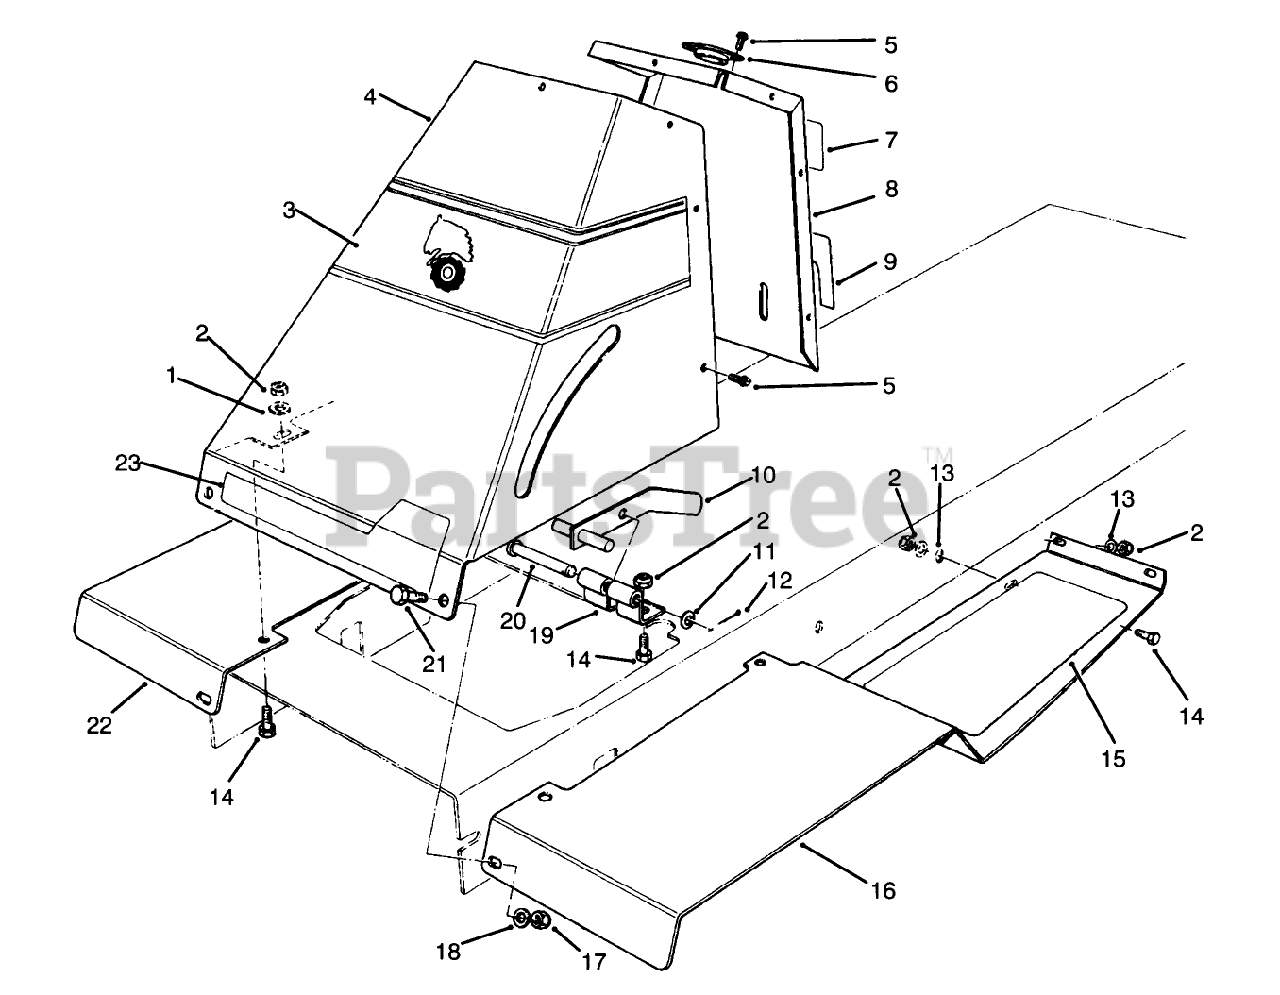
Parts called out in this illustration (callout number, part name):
1	WASHER-FLAT
2	NUT-LOCK, NI
3	DECAL - STEERING SUPT
5	SCREW-HWHTF
6	GUIDE-STRG SHAFT
7	DECAL-DANGER
9	PARK BRAKE DECAL
10	PARKING BRAKE WA *B
11	WASHER-FLAT
12	PIN-COTTER
13	WASHER-PLAIN
14	SCREW-HH
15	FOOT TREAD L.H.
17	NUT-LOCK, NI
18	WASHER-FLAT
20	PIN-CLEVIS
21	SCREW-HH
